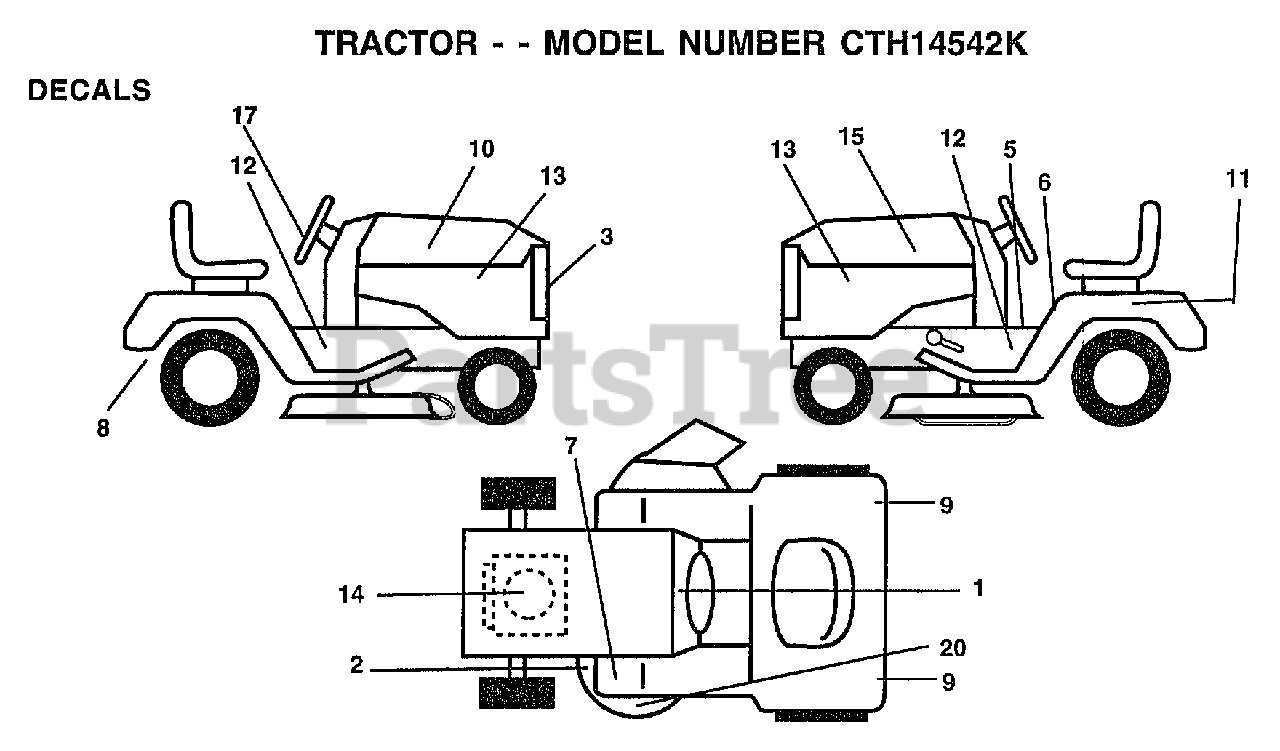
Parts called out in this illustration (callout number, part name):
1	"DECAL-INST,OPER"
2	"DECAL-SCHEM,BELT"
3	DECAL GRILLE
5	DECAL BRAK PARK
6	"DECAL DANGER,FEND"
8	DECAL BY PASS LT HYDRO
9	REFLECTOR-TAIL YT
10	DECAL HOOD RH
11	DECAL.BATRY.3-3908
12	"DECAL CHASSIS 42"""
13	DECAL SIDE PANEL
14	DECAL.ENGINE
15	DECAL HOOD LH
17	DECAL INST STG WH
20	"DECAL,ENVIRO DECK"
